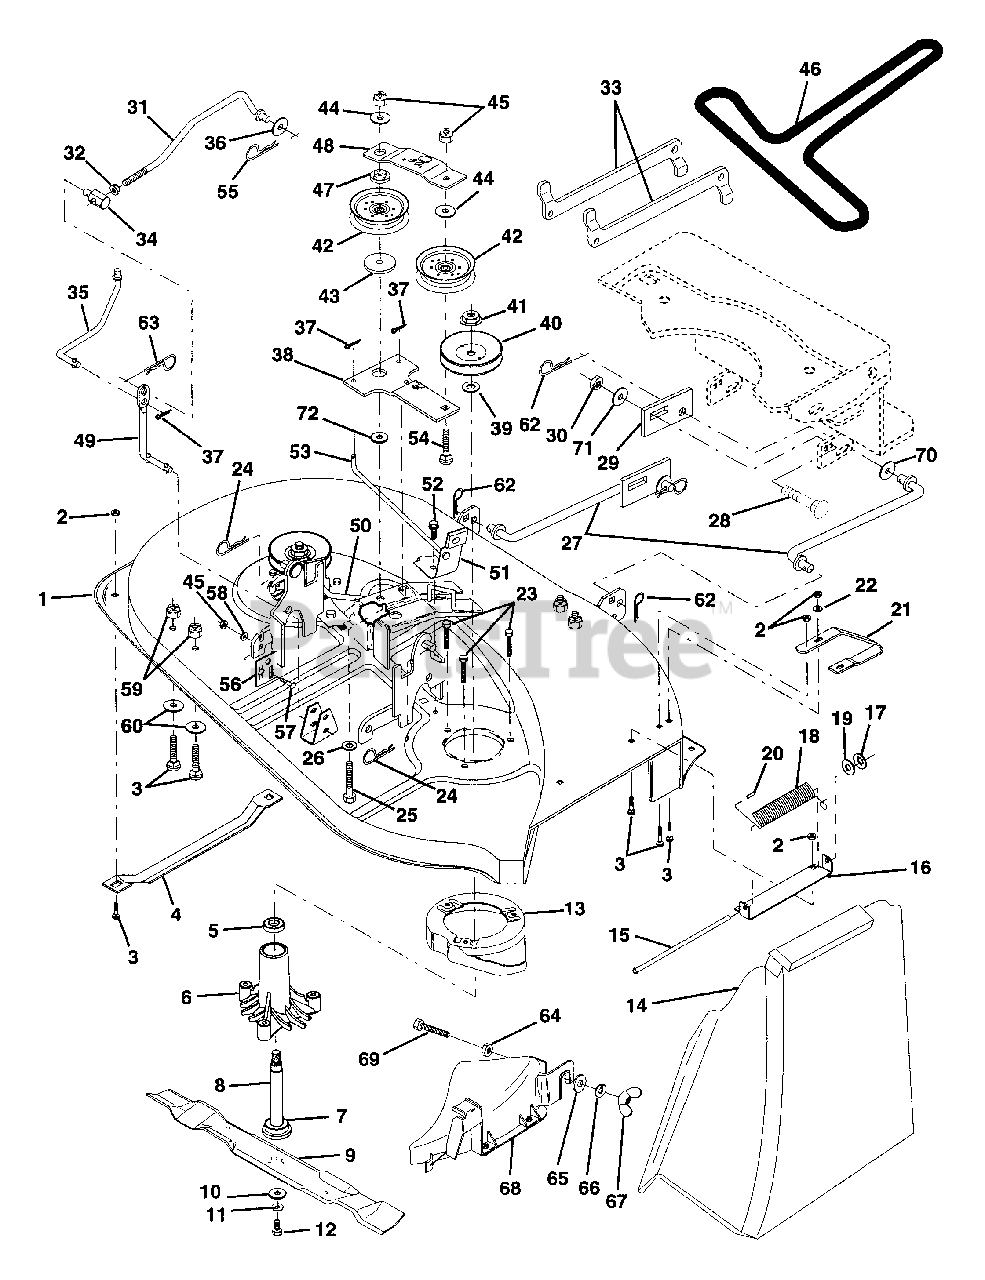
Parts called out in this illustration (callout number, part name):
1	Mower Deck Assembly
2	Nut, Lock Hx w/Ins 5/16-18
3	Bolt, Carriage 5/16-18 x 3/4
4	Runner, L.H.
6	Housing, Mandrel
8	Shaft and Bearing Assembly, Mandrel
10	Washer, Hardened
11	Washer, Lock 3/8
12	Bolt, Hex 3/8-24 x 1-1/4 Grade 8
13	Stripper, Mower, Vented
14	Shield, Deflector
15	Rod, Hinge
16	Bracket Assembly, Deflector
18	Spring, Deflector
19	Washer 11/32 x 5/8 x 16 Gauge
20	Cap, Sleeve
21	Runner, R.H.
22	Washer 11/32 x 3/4 x 16 Gauge
23	Bolt 5/16-18 x 1.25
24	Retainer, Spring
25	Bolt, Hex 3/8-16 x 2-1/4
26	Washer 13/32 x 1 x 12 Gauge
27	Link Assembly, Front
28	Bolt RDHD SQNK 3/8 - 16 x 1
29	Plate Slide Link
30	Nut, Lock Hex w/washer 3/8 - 16
31	Clutch Rod, Primary
32	Nut, Hex, Jam 3/8-16
33	Arm, Suspension, Rear
34	Trunnion 3/8-16
35	Clutch Rod, Secondary
36	Washer 13/32 x 13/16 x 16 Gauge
37	Pin, Cotter 3/32 x 3/4
39	Washer .150 Thick
40	Pulley, Mandrel
41	Nut, Flangelock 9/16
42	Pulley, Flat Idler
43	Spacer, Retainer
44	Washer 13/32 x 1 x 12 Gauge
45	Nut, Lock Hex w/Wsh 3/8-16
46	Belt
47	Spacer, Idler Arm
48	Stiffener, Idler Arm
49	Rod, Pivot
50	Rod, Brake, L.H.
51	Brake Assembly
52	Screw, Hex Washer Head, Thd., Roll. 5/16-18 x 3/4
53	Rod, Brake, R.H.
54	Bolt, Carriage 3/8-16 x 1-3/4 Grade 5
55	Spring, Retainer
56	Adjustment Plate, Rear Link, L.H.
57	Bolt, Carriage 3/8-16 x 1
58	Washer 13/32 x 3/4 x 12 Gauge
59	Locknut, Hex, with Washer Insert 5/16-18
60	Washer 11/32 x 11/16 x 12 Gauge
62	Retainer Spring
63	Retainer Spring
64	Nut, Centerlock 3/8 - 16
65	Washer 13/32 x 1-1/4 x 16 Ga.
66	Washer Lock 3/8
68	Cover Asm Mulching
69	Bolt 3/8 - 16 x 1-1 /4
70	Washer 1/2 x 1-1/4 x 16 Ga.
71	Washer Flat 13/32 x 1 x 10 Ga.
72	Washer Hardened
